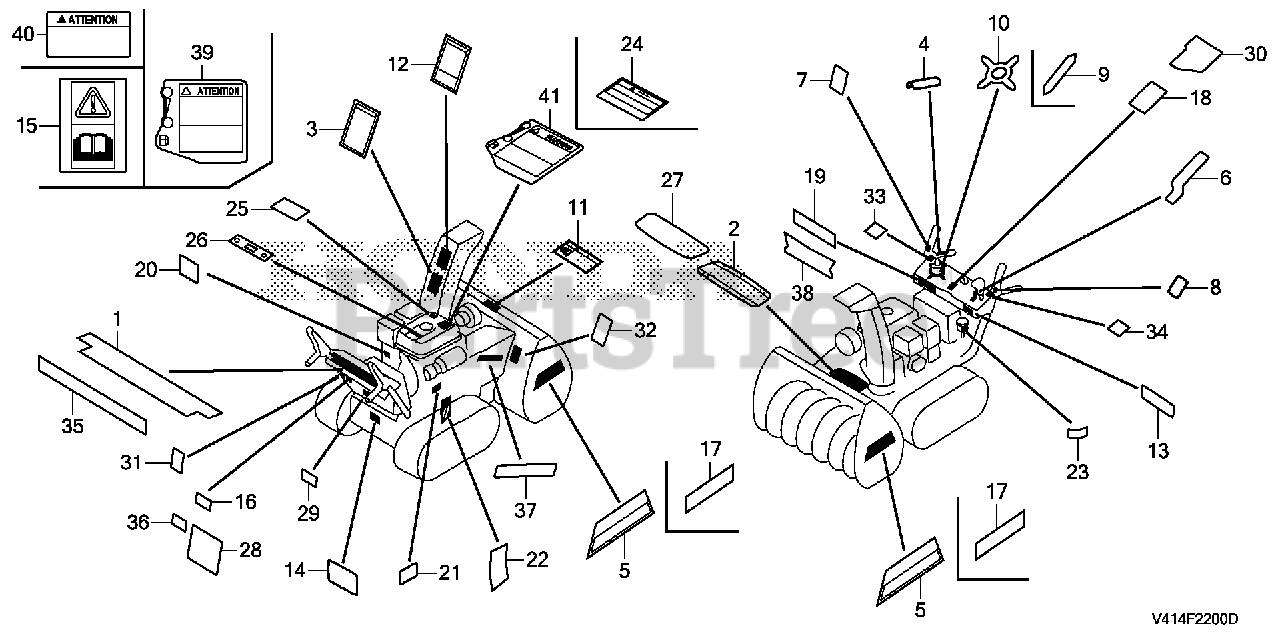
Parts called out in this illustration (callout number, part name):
1	LABEL, OPERATION
3	LABEL, WARNING (ENGLISH)
5	MARK, STRIPE
6	MARK, CHANGE INDICATION
7	MARK, AUGER CLUTCH (ENGLISH)
8	MARK, CLUTCH (ENGLISH)
9	MARK, CHUTE CONTROL OPERATION (ENGLISH)
11	MARK, HOUSING DANGER (ENGLISH)
12	MARK, DISCHARGE DANGER (ENGLISH)
13	MARK (H.S.T.)
14	MARK, INDICATION (H.S.T.)(ENGLISH)
16	MARK, CHOKE INDICATION (ENGLISH)
18	MARK, THROTTLE (ENGLISH)
19	MARK B, HONDA
20	MARK, FUEL INDICATION (ENGLISH)
21	MARK, OIL CAUTION (ENGLISH)
22	MARK, HEIGHT ADJUSTING
23	LABEL, OIL RECOMMENDATION (ENGLISH)
24	MARK, OPERATOR CAUTION (ENGLISH)(MADE IN JAPAN)
25	MARK, EX. CAUTION (ENGLISH)
26	MARK, FUEL INDICATION (PICTOGRAPH)
